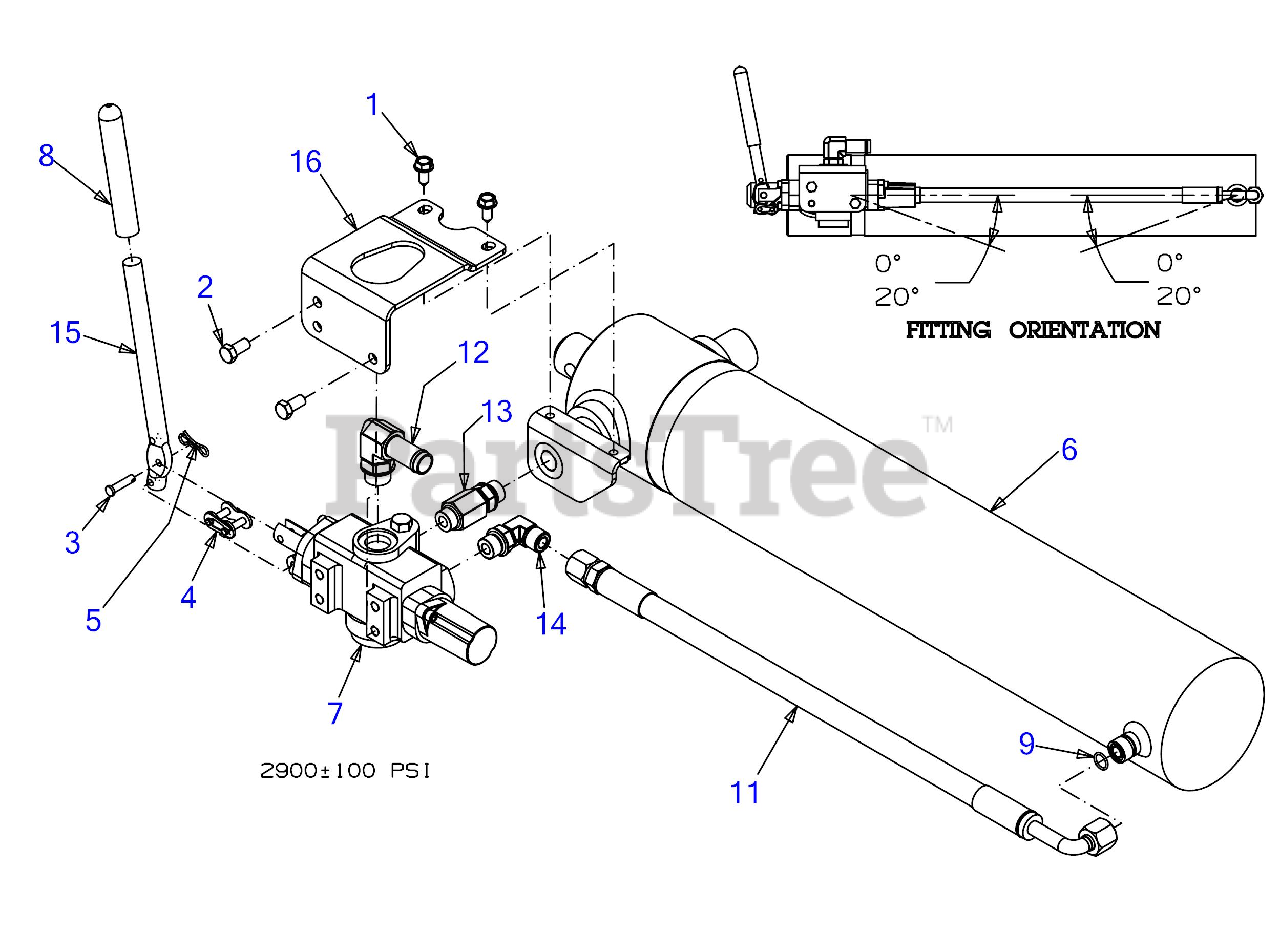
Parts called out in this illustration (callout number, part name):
1	SCREW 5/16-18 x .750
2	SCREW 3/8-16 x .75 GR 5
3	CLEVIS PIN .25 x 1.00
4	VALVE HANDLE LINK
5	BOW TIE COTTER PIN 1/4-5/16
6	HYDRAULIC CYLINDER
7	LOGSPLITTER VALVE
9	O-RING
11	HYDRAULIC HOSE
12	HYDRAULIC FITTING
13	HYDRAULIC FITTING
14	HYDRAULIC FITTING
15	CONTROL VALVE HANDLE
16	VALVE BRACKET
